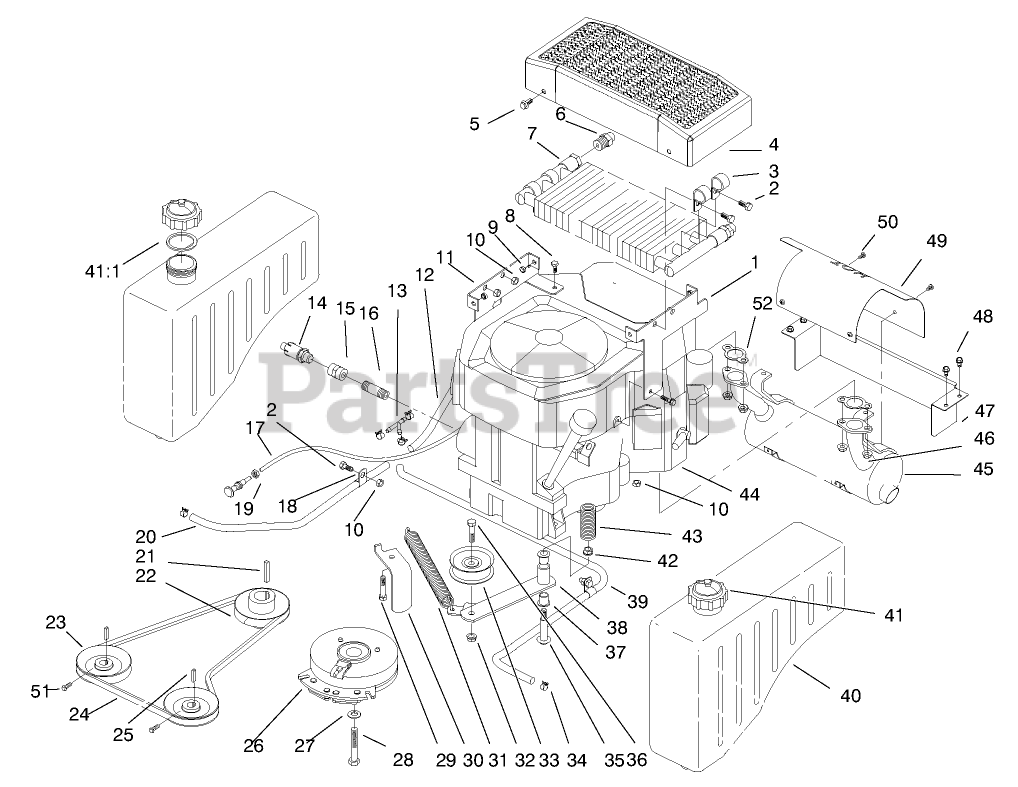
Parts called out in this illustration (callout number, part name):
1	Bracket-Cooler
2	SCREW-HH
3	CLAMP-R
4	Cooler Shroud ASM
5	SCREW-HHF
6	FITTING-ADAPTER
7	COOLER ASM
8	SCREW-HH
9	INSERT-NUT
10	NUT-LOCK, NI
11	Bracket-Cooler
12	HOSE - FUEL
13	FITTING-FUEL 45-Y
14	VALVE-DRAIN, OIL
15	3/8 X 1 COUPLER
16	NIPPLE
17	CONTROL - CHOKE
18	CLAMP-R
19	NUT-HJ
20	FUEL HOSE
21	KEY-SQUARE
22	PULLEY - PUMP
23	PUMP PULLEY
24	V-BELT, PUMP
25	KEY-PUMP
26	CLUTCH - ELECTROMAGNET
27	WASHER-FLAT
28	SCREW-HH
29	SCREW-HH
30	Stop-Clutch
31	SPRING - EXTENSION
32	NUT-LOCK, NI
33	PULLEY-IDLER
34	CLAMP-HOSE
35	WHEEL BOLT
36	SCREW-HH
37	BUSHING-FLANGE
38	Lever-Idler
39	HOSE - GAS
40	ASS'Y-FUEL TANK
41	ASSY FUEL CAP
41:1	GASKET-GAS CAP
42	NUT-LOCK
43	SPRING-COMPRESSION
44	Engine ASM
45	MUFFLER - ENGINE
46	NUT-HF
47	SHIELD - HEAT
48	SCREW-HWH
49	SHIELD - HEAT
50	SCREW
51	SCREW-SET
52	GASKET-EXHAUST
